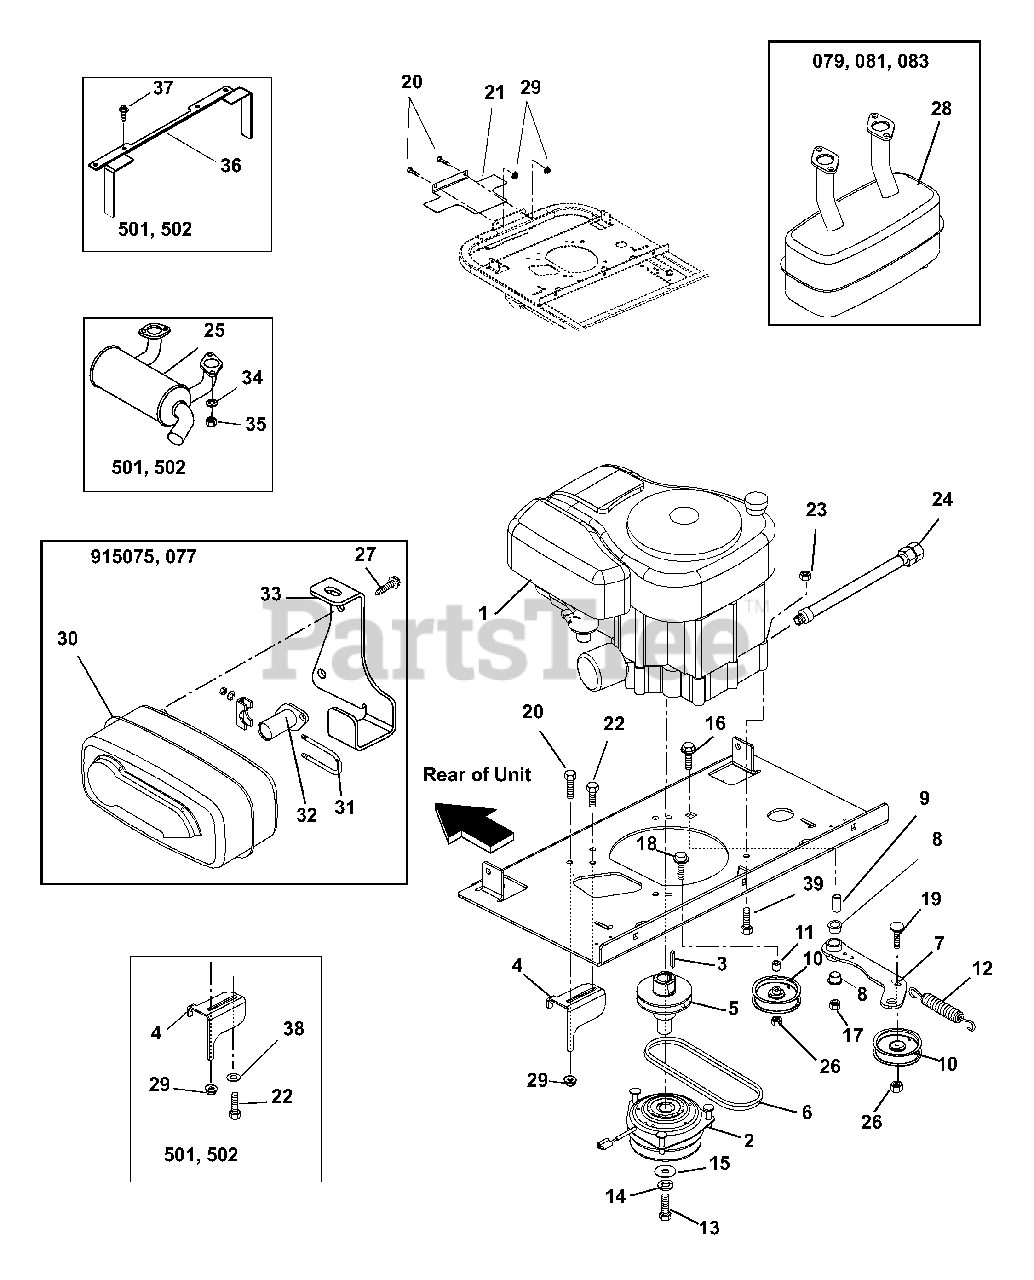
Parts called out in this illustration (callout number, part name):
1	ENGINE, 16 HP KOHLER SINGLE
1	ENGINE, 18 HP KOHLER SINGLE
1	ENGINE, 20 HP KOHLER COUR TWIN
1	ENGINE, 19HP KOHLER
1	ENGINE, 23 HP KOHLER COUR TWIN
1	ENGINE, 23HP KOHLER
1	ENGINE, 25 HP KOHLER COUR TWIN
1	ENGINE, 15HP KAW FH451V
1	ENGINE, 17 HP KAWASAKI FH500V
2	CLUTCH,ELECTRIC PTO
2	ELECTRIC CLUTCH/BRAKE (3.4AMP)
3	KEY-SQ .25 X 1.50 X .25 SAE
4	STOP, CLUTCH
5	EXTENSION, CRANK SHAFT
6	BELT,HA WRAPPED
7	WMT, IDLER ARM
8	BSHG-FLG 0.75X0.875X.625X1.125
9	BSHG-SLV .500X.750X1.560
10	IDLER-FLAT 4.00 X .38 NWHAMSHR
11	BSHG,SPCR .41 X .75 X .88 PM
12	SPRING, EXT
13	BLT-HEX .44-20X4.50 GR8 YWZC
14	@WSHR-LK .44X.109 REG YWZC
15	WSHR-FL-STL .469X2.00X.25 YWZC
16	@BLT-HEX .50-13X2.50 GR5 YWZC
17	@NUT-LK-TOP-FLG .50-13 YWZC
18	@BLT-RDHDSQNK .38-16X2.00 G5YZ
19	@BLT-RDHDSQNK .38-16X1.25 G5YZ
20	@BLT-HEX .38-16X1.00 GR5 YWZC
21	HEAT SHIELD, TWIN
22	@SCR-TAP .38-16X1.00 HWH TR YZ
22	@BLT-HEX .31-18X1.75 GR5 YWZC
22	@BLT-HEX .38-16X1.00 GR5 YWZC
23	@NUT-LK-NYL-FLG .31-18 YWZC
24	HOSE, HYD .38-15-0K M6N0-F6J0
25	MUFFLER, KAW. (COMPACT-Z)
26	@NUT-LK-CTR-JAM .375-16 YWZC
27	@SCR-TAP .25-20X.50 HWH TR YWZ
28	MUFFLER
29	@NUT-LK-NYL-FLG .38-16 YWZC
30	MUFFLER, KOHLER SINGLE
31	MUFFLER CLAMP
32	WMT, MANIFOLD
33	BRKT, MUFFLER (KOHLER COURAGE)
34	@WSHR-LK .31X.078 REG YWZC
35	NUT-HEX M8-1.25 YWZC
36	HEAT SHIELD
37	@SCR-TAP .31-18X.50 HWH TR YWZ
38	WSHR-FL-STL .328X1.0X.094 YWZC
39	@SCR-TAP .38-16X1.00 HWH TR YZ
39	@BLT-HEX .31-18X1.75 GR5 YWZC
